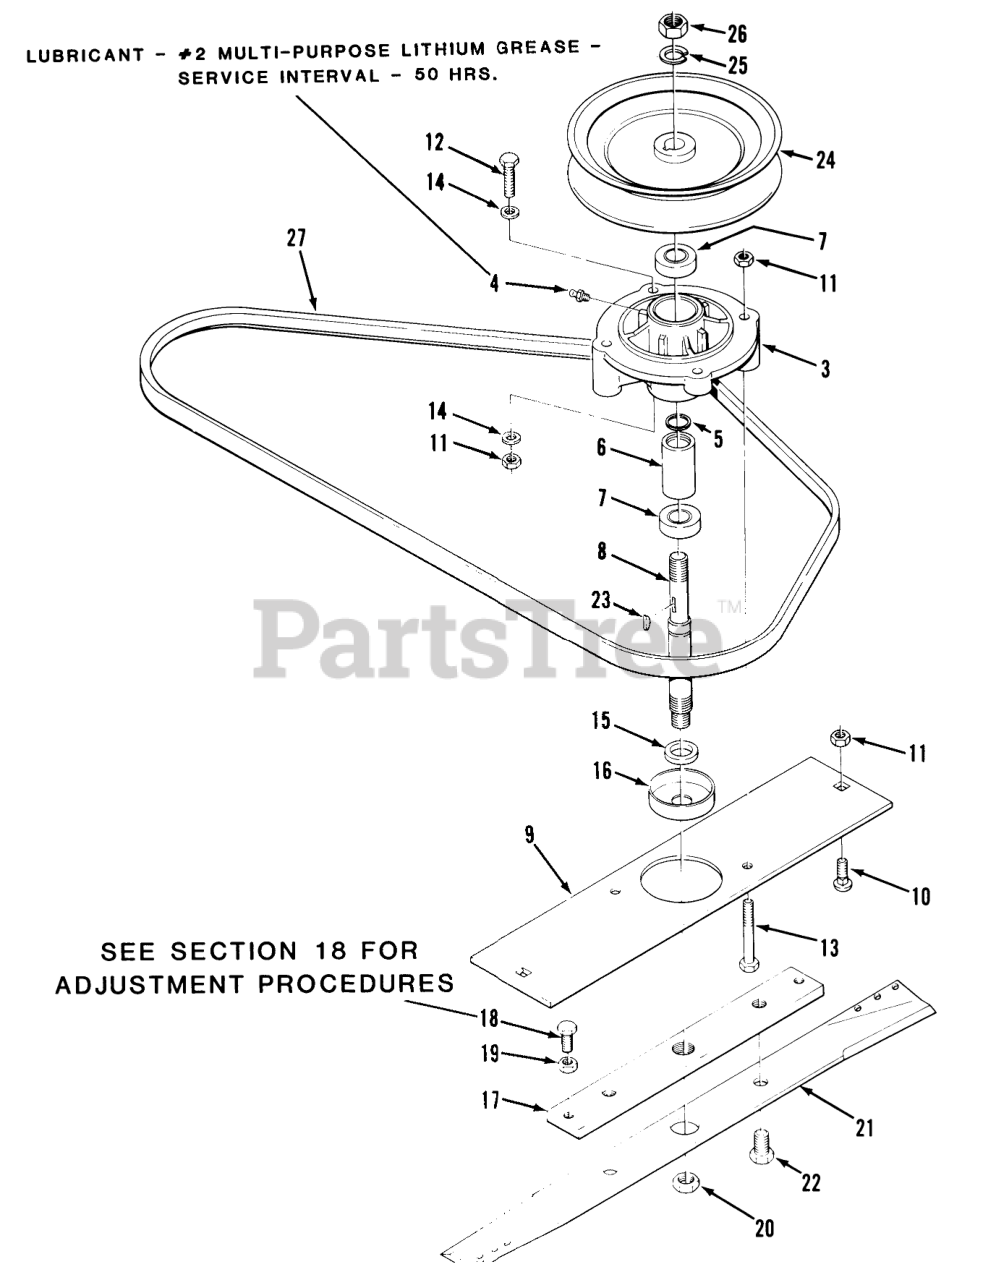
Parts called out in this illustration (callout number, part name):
1	Spindle Assy (Includes items 3 thru 8)
3	HOUSING-SPINDLE
4	Fitting-Grease
5	SNAP RING
7	BALL BEARING
8	SHAFT
9	BAR R
10	Bolt
11	NUT
12	Bolt
13	Bolt
14	Washer
15	SPACER-BLADE
16	CUP-SPINDLE
17	BAR-BLADE R
18	Bolt
19	NUT-HEX, JAM
20	Jam Nut
21	Blade
22	HEX BOLT 1/2-13X3/4
23	KEY-HI-PRO
24	PULLEY
25	Lockwasher
26	NUT-HEX
27	V-BELT DRIVE
